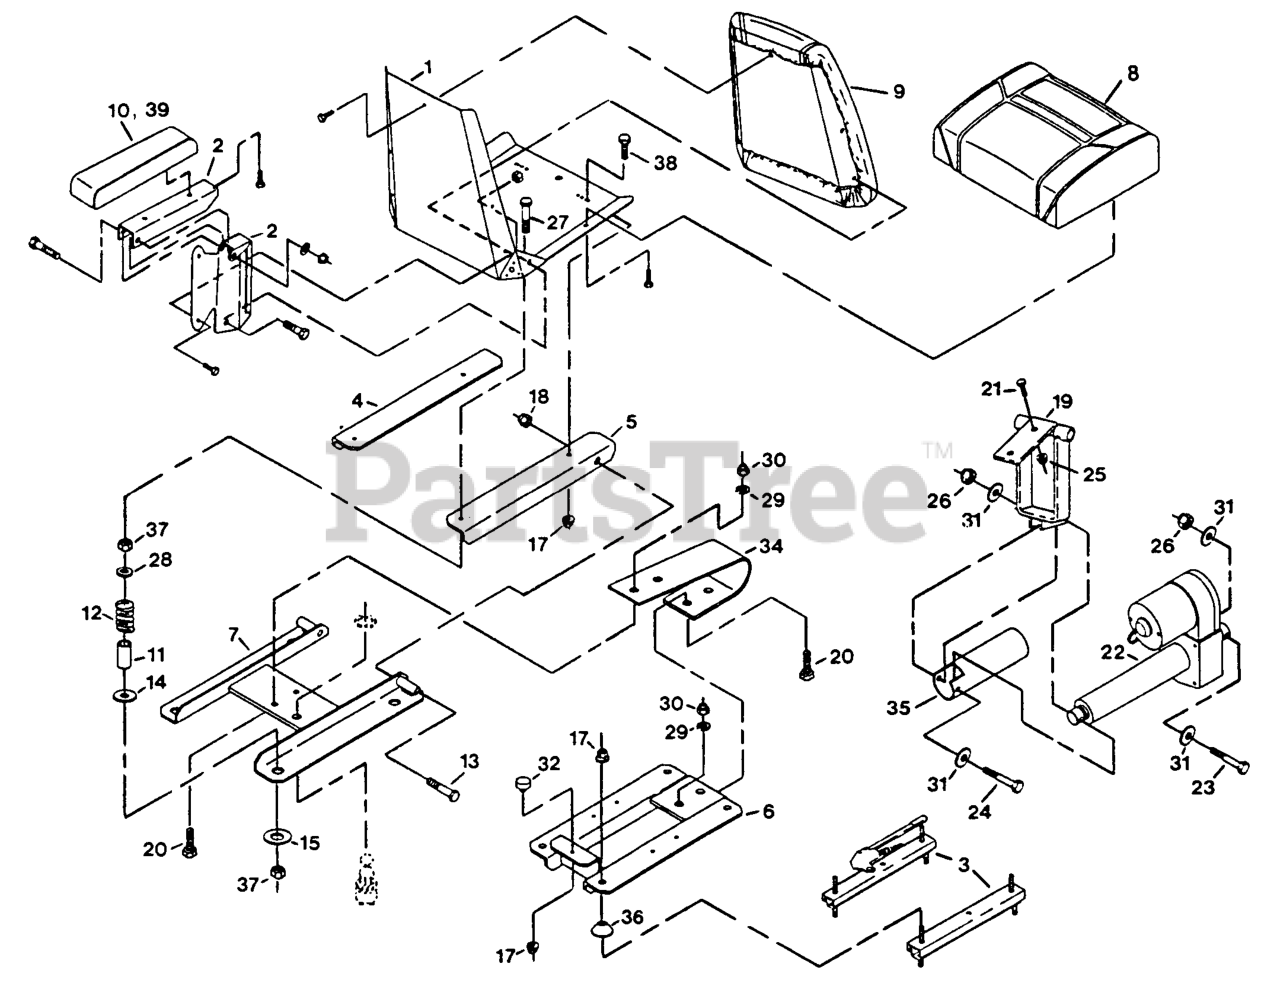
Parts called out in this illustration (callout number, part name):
4	RAIL,SEAT LH
5	RAIL,SEAT RH
6	WLD,RAIL BASE
11	BUSHING,SPRING GUIDE
12	SPRING-INDICATOR, REVERSE
16	SWITCH,PUSH BUTTON
27	BOLT,TAP HH
32	BUMPER-RUBBER
34	SPRING,RANGER SEAT
35	GUARD,ACTUATOR
36	SPACER-TRACK
